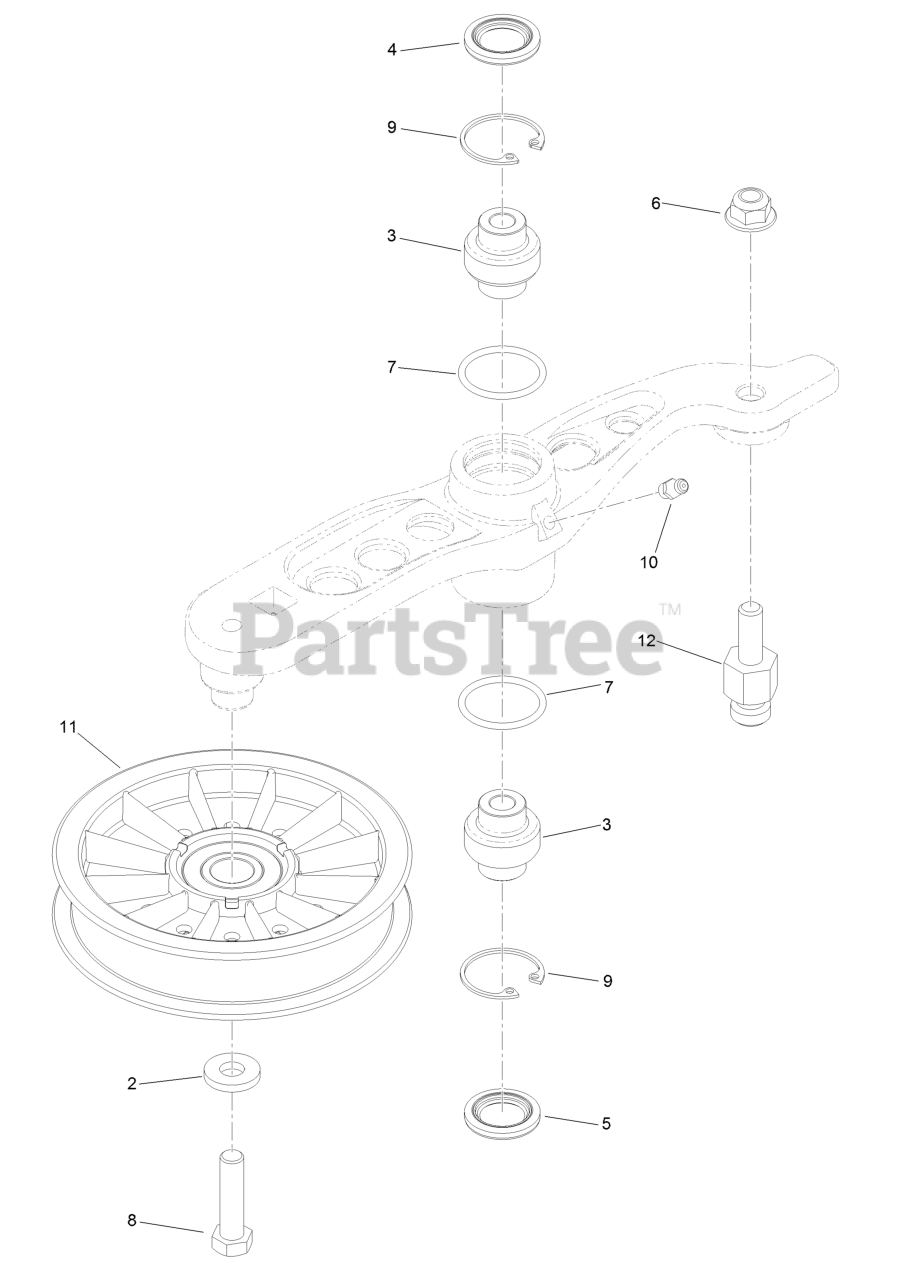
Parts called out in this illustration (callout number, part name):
3	Bearing-Spherical
4	Seal-Lip, Double
5	Seal-Lip, Single
6	Nut-Flange, NI
8	Screw-HH
9	Ring-Snap
10	Fitting-Grease
11	Pulley-Idler
12	Pin-Anchor, Spring
